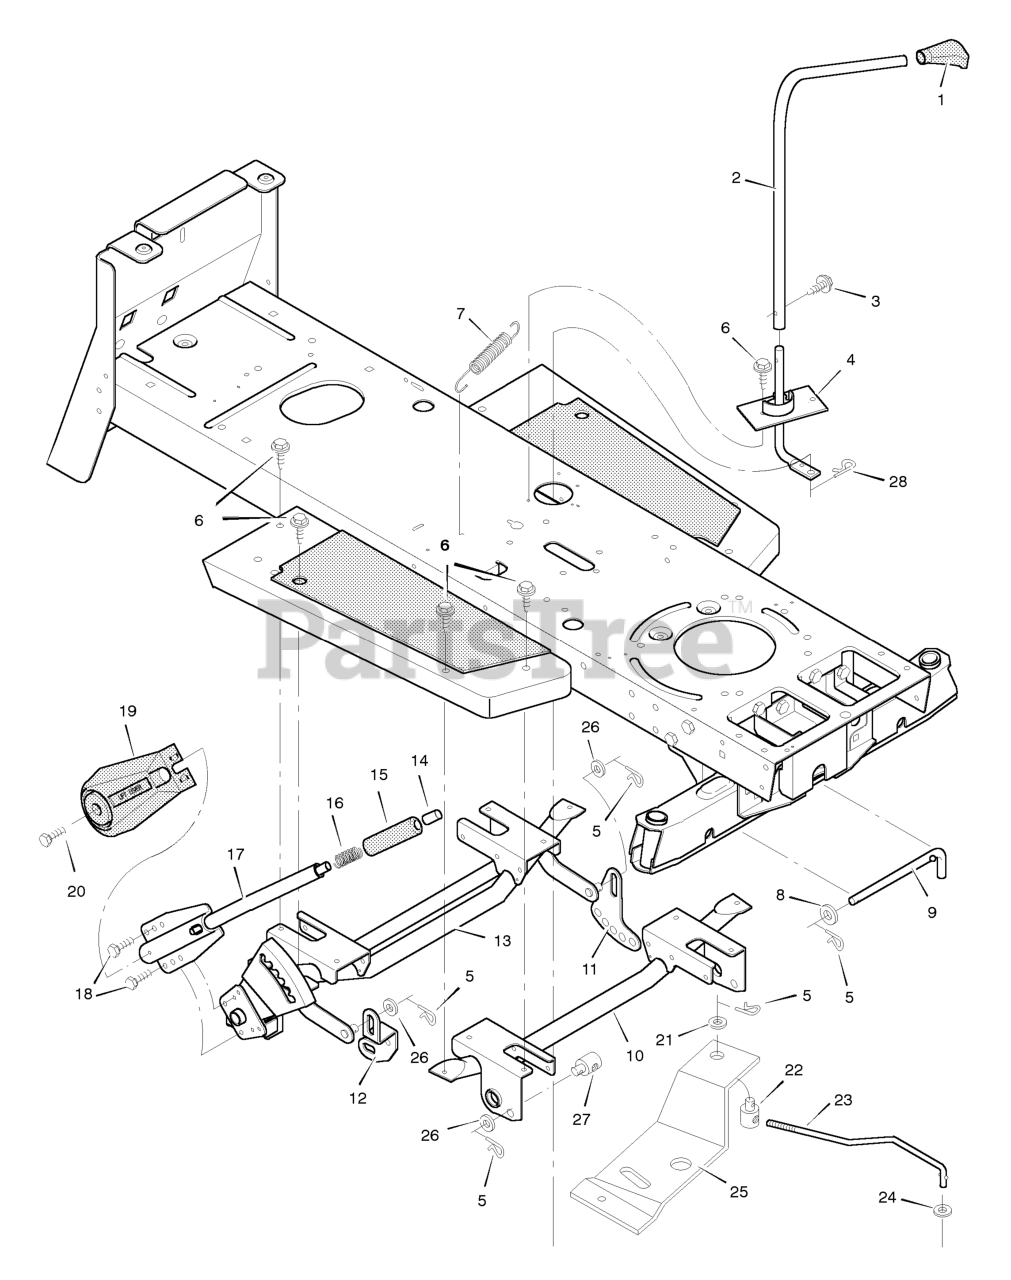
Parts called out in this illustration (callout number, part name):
1	Grip
2	Lever, Blade Control
3	Screw, Hex
4	Control Assembly, Blade
5	Pin, Hair
7	Spring, Extension
9	Pin, Pull
10	Support Assembly, Front
11	Plate, Adjuster
12	Link, Suspension
13	Support, Lifter
14	Button, Push
16	Spring, Compression
17	Handle Assembly
19	Cover, Lift Lever
22	Nut, Adjusting
23	Rod, Blade Control
24	Washer
25	Bracket, Pivot
27	NUT, Adjusting, 1/2-13
28	Pin, Hair
